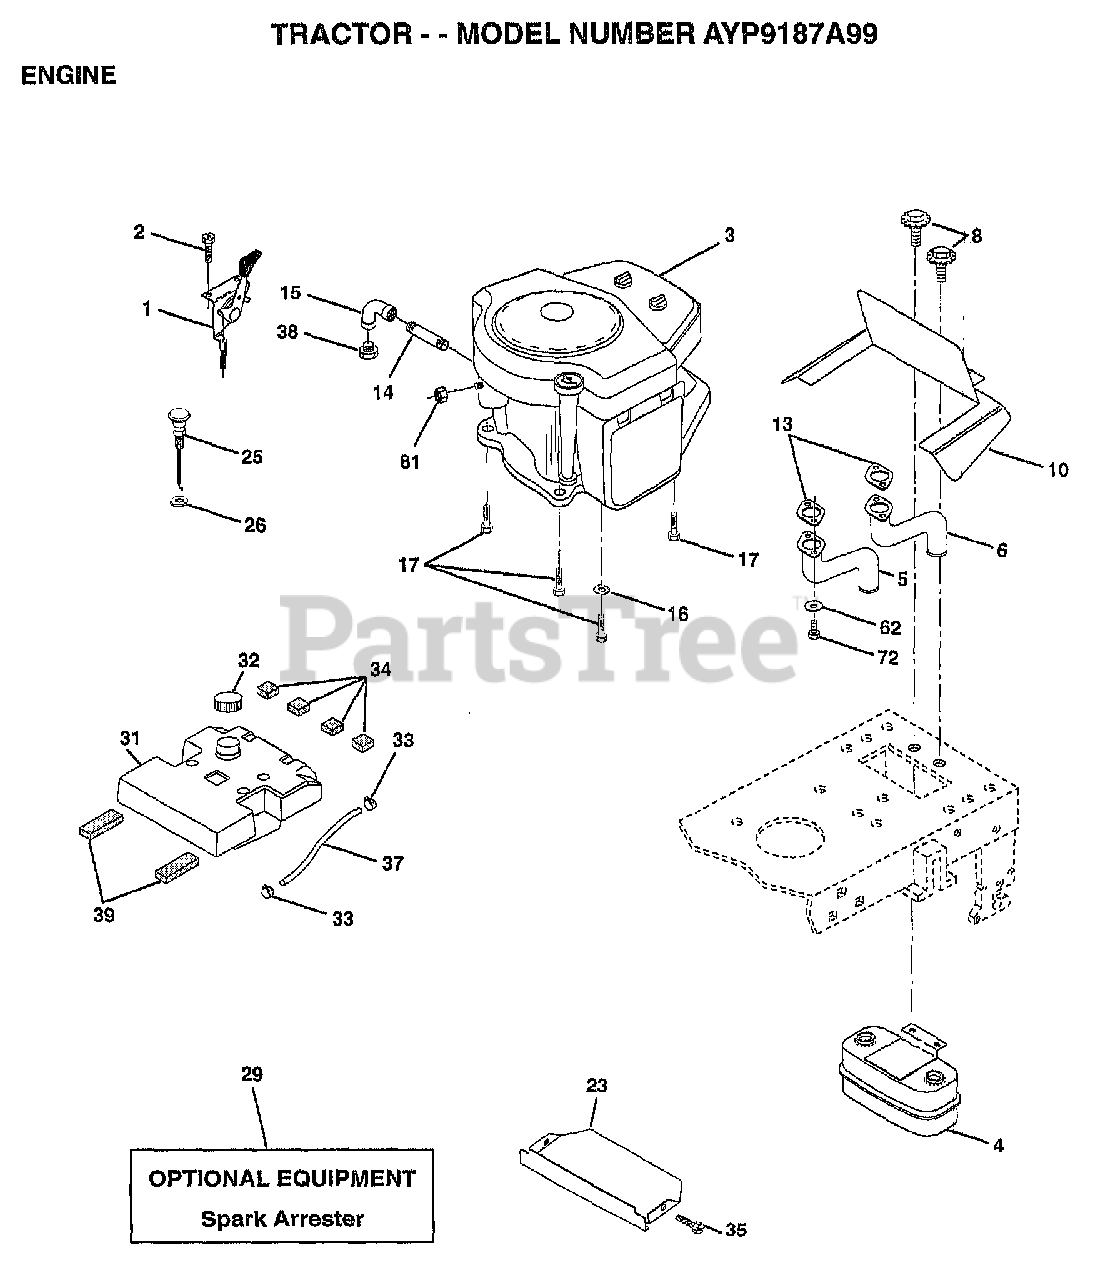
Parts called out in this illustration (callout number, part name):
1	CONTROL THROT. LH
2	SCREW LT
4	MUFFLER.TW.LOTONE
5	TUBE MANIFOLD RH
6	TUBE MANIFOLD LH
7	CLAMP.TUBE.DBL.EN
8	BOLT.5/16-18.UNC
10	SHIELD.BROWNING
14	PIPE NIPPLE LT
15	ELBOW
16	LOCKWASHER
17	SCREW LT
23	SHIELD.BRN/DBR.GD
25	CONTROL.CHOKE.37
26	"NUT,KEPS 3/8-24IM"
31	"TANK.FUEL,3.5 GAL"
32	CAP ASM FUEL
33	HOSE CLAMP
34	PAD-SPACER LT
35	SCREW
37	FUEL LINE T
39	PAD IDLER TI
62	LOCKWASHER
72	SCREW
81	NUT
